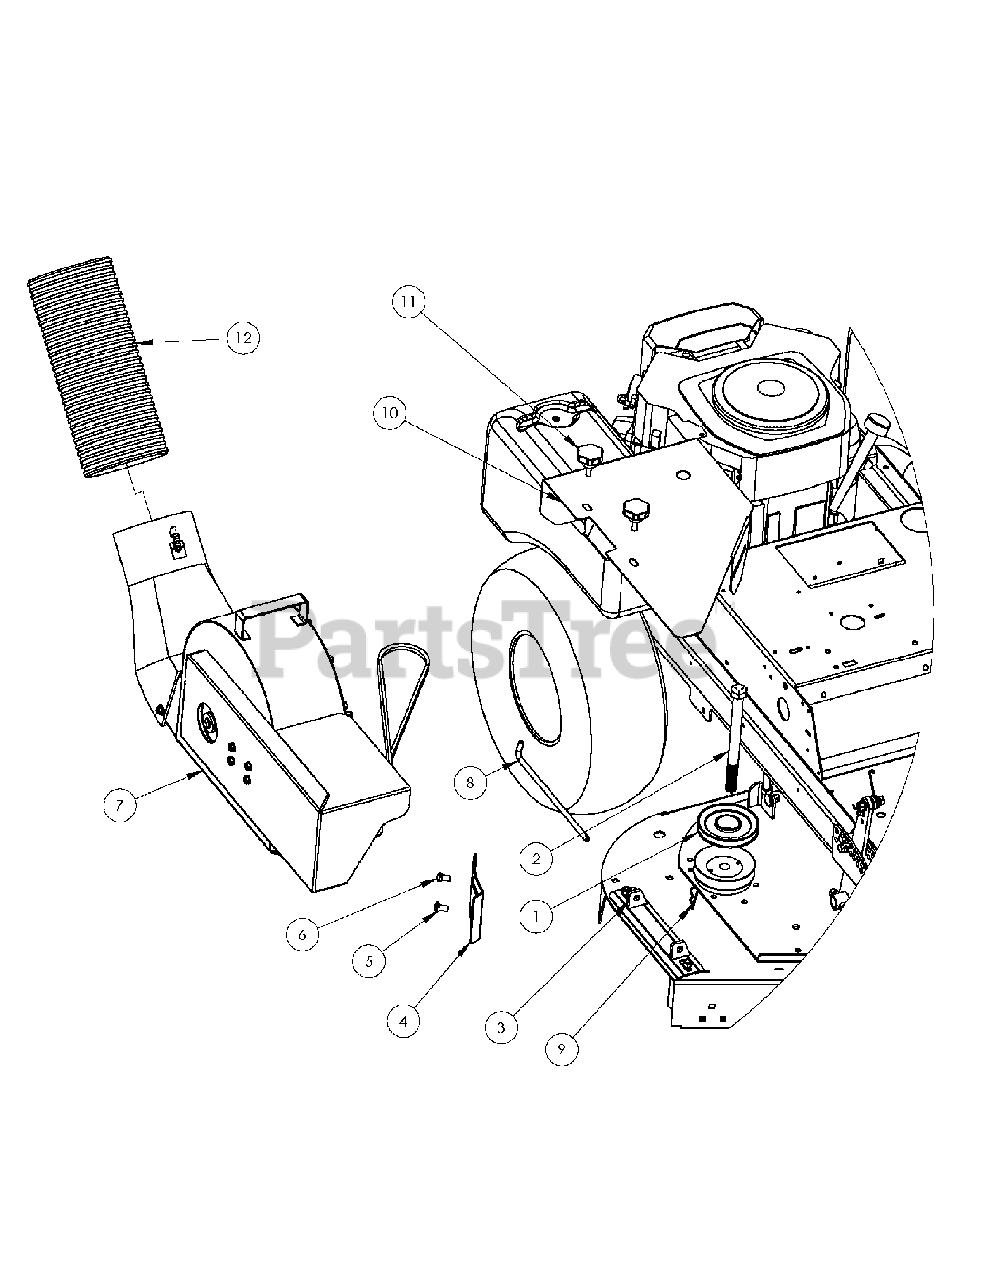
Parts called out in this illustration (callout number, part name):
1	CATCHER MOUNT
2	EXISTING BOLT
3	DECK MOUNTING ADAPTOR
4	DECK PLATE
5	EXISTING BOLT
6	CARRAGE BOLT, 3/8" - 16 X 1" LONG
7	SEE BLOWER ASSEMBLY
8	MOUNTING PIN
10	BELT GUARD
11	MOUNTING KNOBS
12	DISCHARGE HOSE
